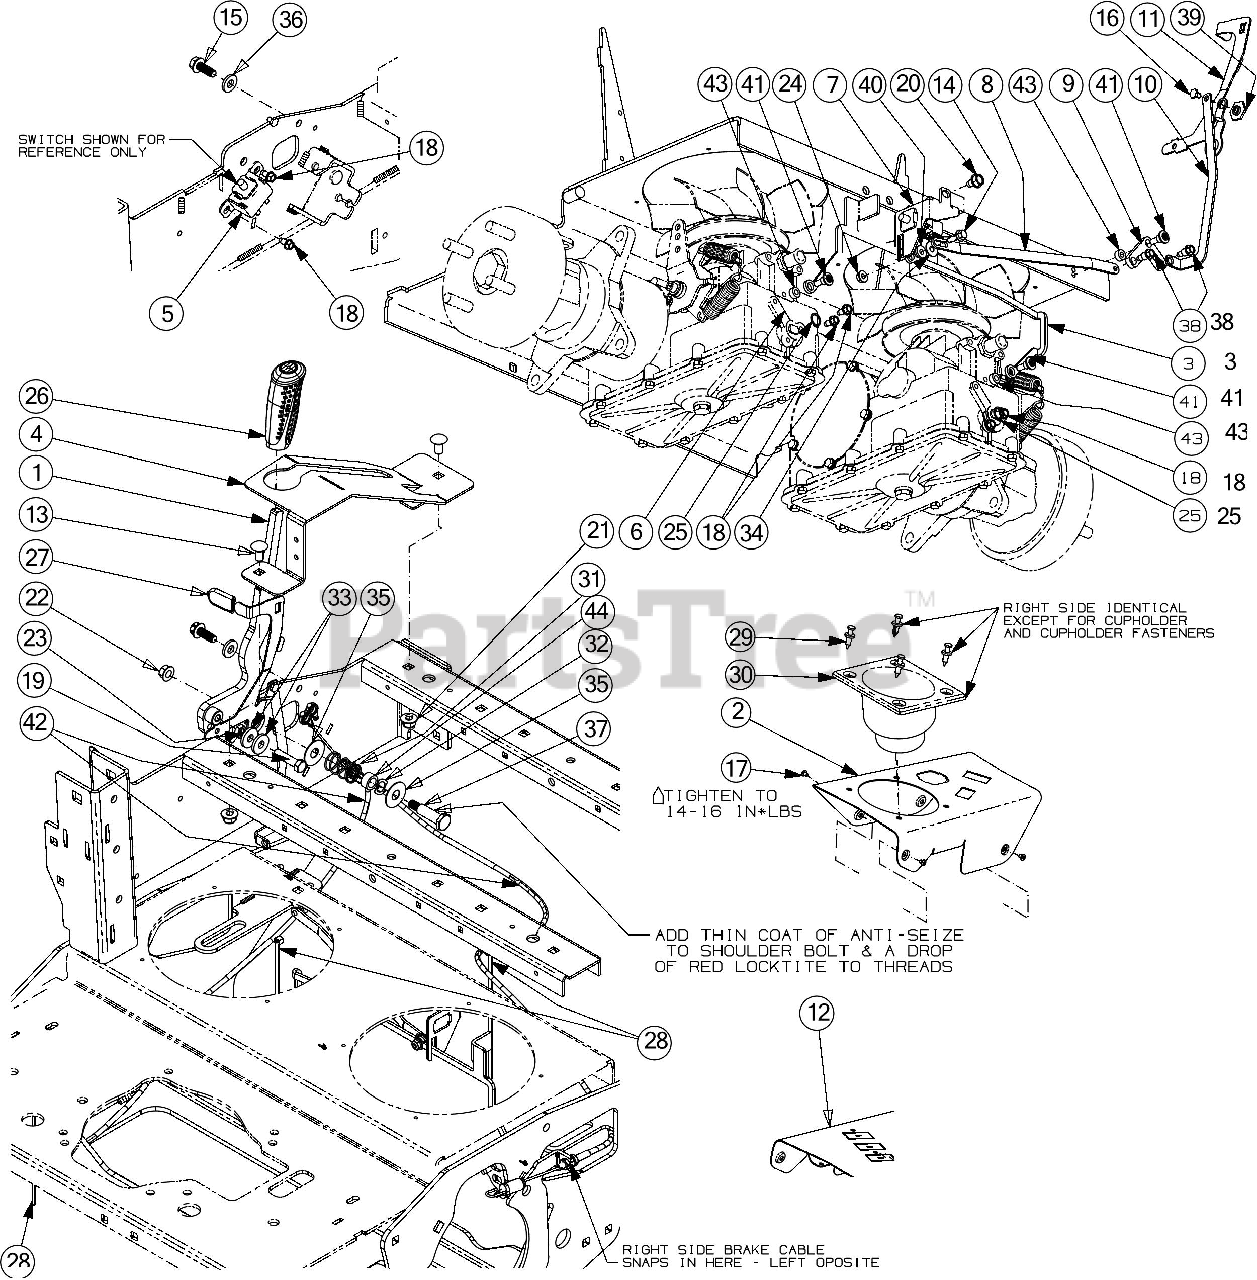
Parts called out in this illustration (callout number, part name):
1	BRAKE HANDLE ASSEMBLY
2	CONTROL PANEL (LH)
3	DUMP VALVE BRACKET
4	BRAKE BOOT BRACKET
5	BRAKE PANEL MOUNT
6	TRANSMISSION BYPASS LEVER
7	NEUTRAL BRACKET
8	ACTUATOR ARM LINK
9	NEUTRAL CONTROL LEVER
10	NEUTRAL ARM LINK
11	RELEASE VALVE LEVER
12	CONTROL PANEL (RH)
13	CARRIAGE BOLT 3/8-16 x .750 GR5
14	SCREW 1/4-20 x .75 GR5
15	SCREW 3/8-16 x 1
16	SCREW M6 x 8MM
17	SCREW #10-32 x .25
18	SCREW 1/4-20 X.500
19	SCREW 3/8-16 x 1.50 GR8
20	SCREW 5/16-18 x .500
22	HEX LOCK NUT
24	LOCK NUT 1/4
25	SNAP RING
27	SEAT ADJUSTER GRIP
28	7" CABLE TIE
29	PLASTIC RIVET
30	CUP HOLDER
31	COMPRESSION SPRING .844X.970X1.50
32	WAVE WASHER
33	FLAT WASHER .385 x 1.00 x .135
34	FLAT WASHER .283 ID x .749 x .030
35	FLAT WASHER
36	FLAT WASHER
37	SHOULDER SCREW .498 DIA x 1.450-THD
38	SHOULDER SCREW
39	SHOULDER SPACER
40	SHOULDER SPACER
41	SHOULDER SCREW .375X.280:1/4-14
42	BRAKE CABLE
